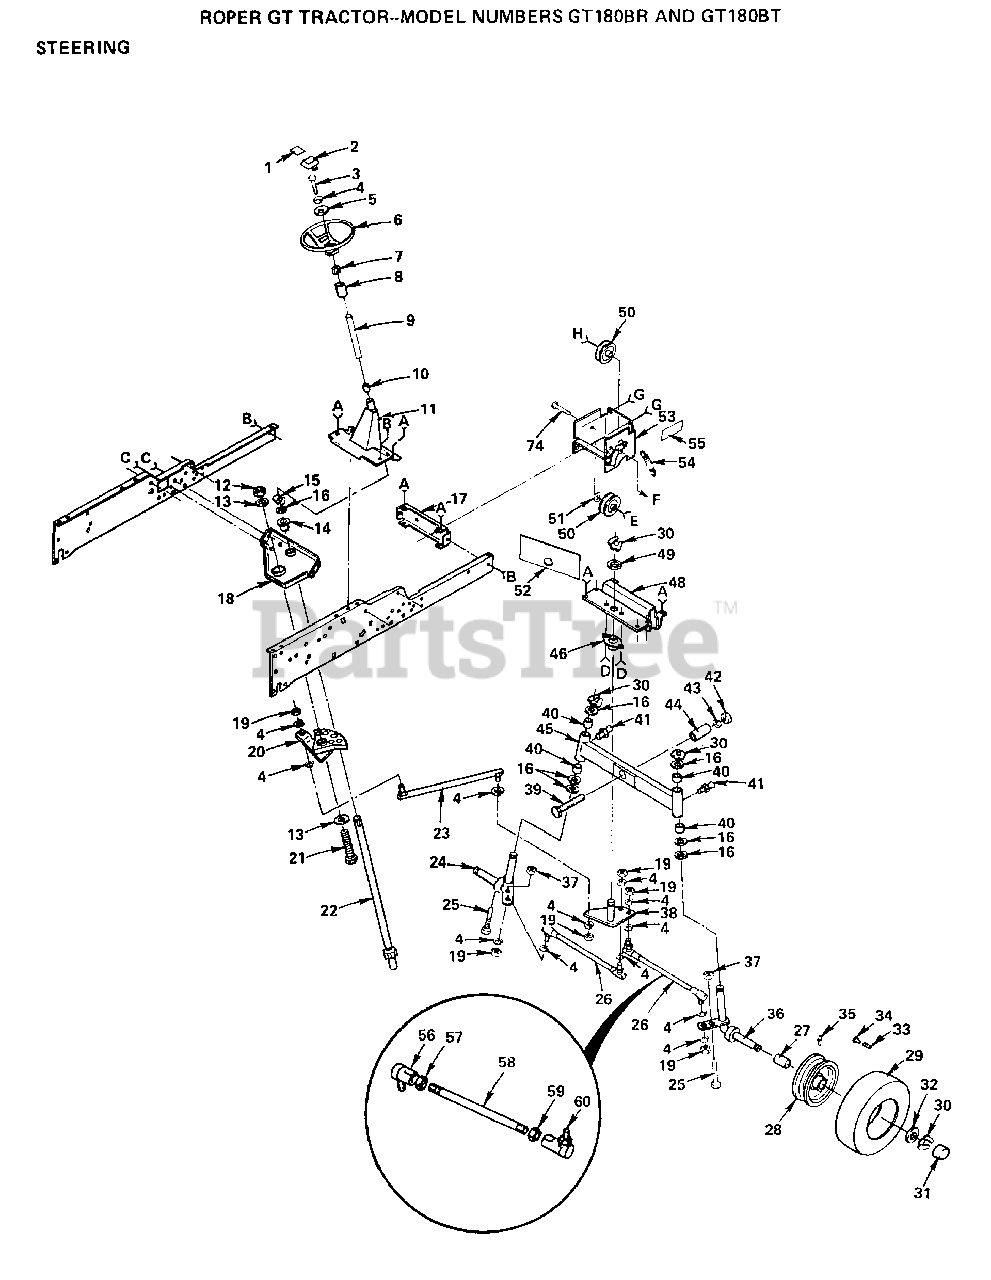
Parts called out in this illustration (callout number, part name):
1	DECAL - STEERING WHEEL
2	INSERT-WHEEL LT
3	BOLT
4	LOCKWASHER
7	ADAPTER LT
9	TUBE
10	"T, BEARING"
11	SUPPORT ASSY T
12	NUT LTV
13	WASHER GT
14	"FLANGE GT, BEAR."
15	KLIP RING
16	WASHER .T
17	FRAME BRACKET GT
21	BOLT
22	SHAFT STEERING GT
24	SPINDLE ASSY T
25	BOLT, HEX 3/8 - 16 X 2
27	"FLANGE, BEARING"
30	RING
31	HUB CAP
33	VALVE CAP
34	VALVE STEM LT
35	FITTING LT
36	SPINDLE RH T
37	NUT
38	"T, BELLCRANK"
39	BOLT
40	BRNG. T
41	ZERK M
42	NUT X
43	WASHER
47	CLIP GTV
48	AXLE BRACKET T
49	WASHER
50	IDLER-INSIDE T
51	WASHER T
54	SPRING
57	NUT
59	NUT
